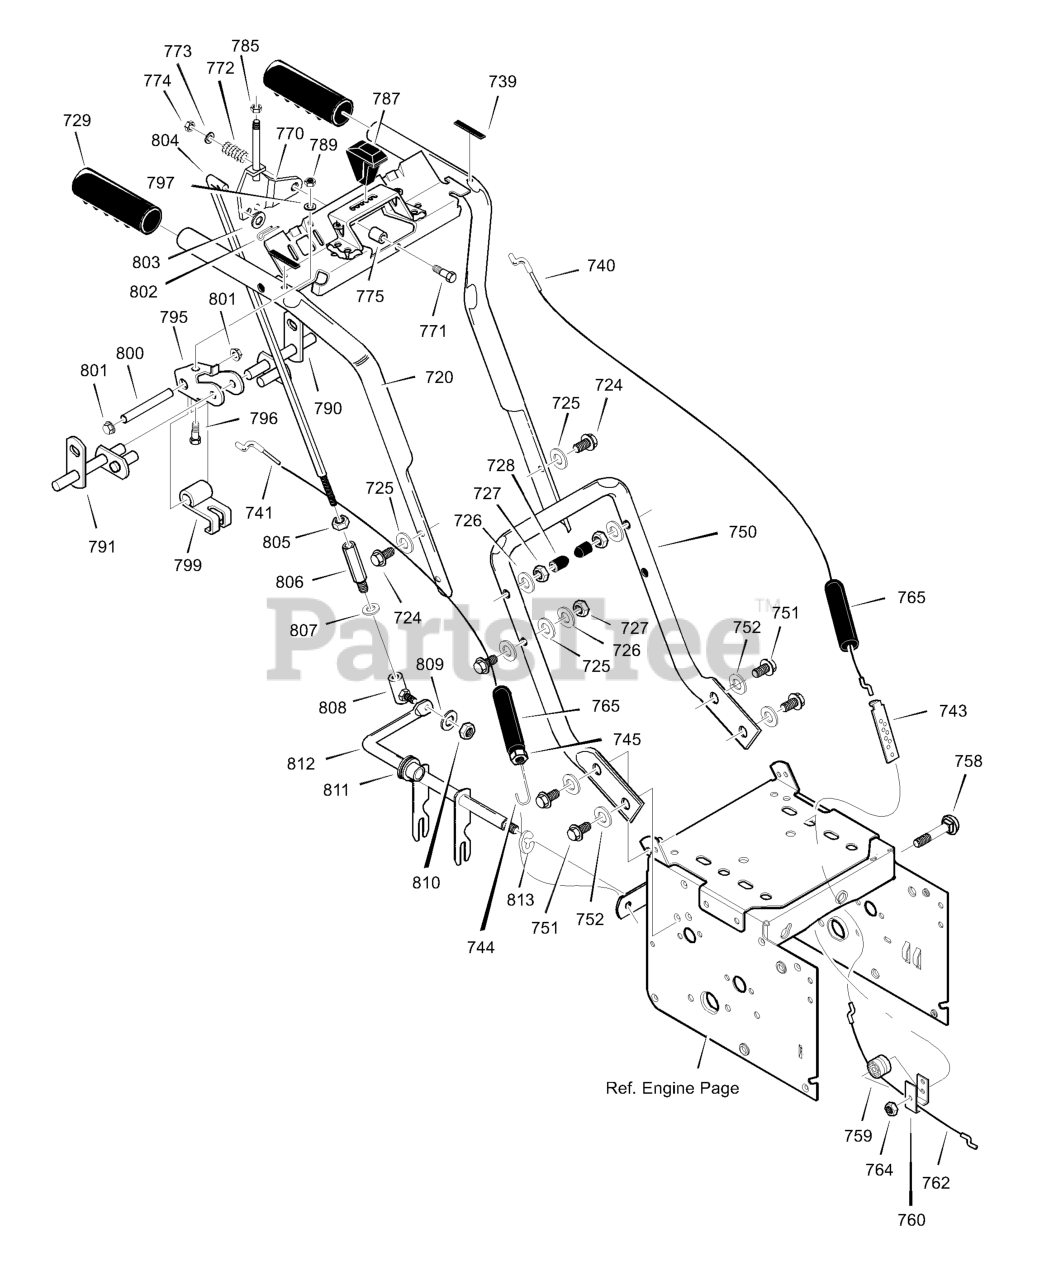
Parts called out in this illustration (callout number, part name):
720	ASSY, HANDLE -UPPER
723	SCREW, 3/8-16 x 2.00
724	SCREW, 3/8-16 x 3.00
725	WASHER, FLAT
726	WASHER
727	NUT, 3/8-16
728	STOP, PLASTIC
729	GRIP, HANDLE
739	BUMPER
740	CABLE, AUGER DR.
741	CABLE, AUGER CLUTCH
743	BRACKET, CABLE ADJUST
744	SPRING, AUGER CLUTCH
745	NUT, 1/4-20 HEX NYLOCK
750	HANDLE, LOWER
751	SCREW, 5/16-18 x 0.75
752	WASHER, SPTLK
754	SCREW, 5/16-18 x 0.75
758	BOLT, HEX 1/4-20 x 1.50
759	SPOOL, CABLE
760	BRKT, SPOOL
762	CABLE, LOWER DRIVE
765	BOOT, CABLE
770	BRACKET, SHIFT
771	SCREW, 3/8-16 x 3.00
773	WASHER, FLAT
774	NUT, 3/8-16 HEX
775	SPACER, SHIFT
785	NUT, 1/4-20 HEX
787	KNOB, SHIFT
790	ROD, ASSY LH
791	ROD, ASSY RH
795	BRACKET, CAM
796	SCREW, 5/16-18 x 0.75
797	WASHER, SPTLK
798	NUT, 5/16-18 HEX
799	CAM LOCK
800	PIN, SPRING PIVOT
801	NUT, PUSH ON
802	PIN, COTTER
803	FLATWASHER
804	ROD, CONTROL
805	NUT, 5/16-24 HEX
806	ADAPTOR, SPEED
807	WASHER
808	JOINT, STEEL BALL
809	WASHER
810	NUT, HEX
811	BEARING, FL
812	ROD, YOKE
813	RETAINER, RING
